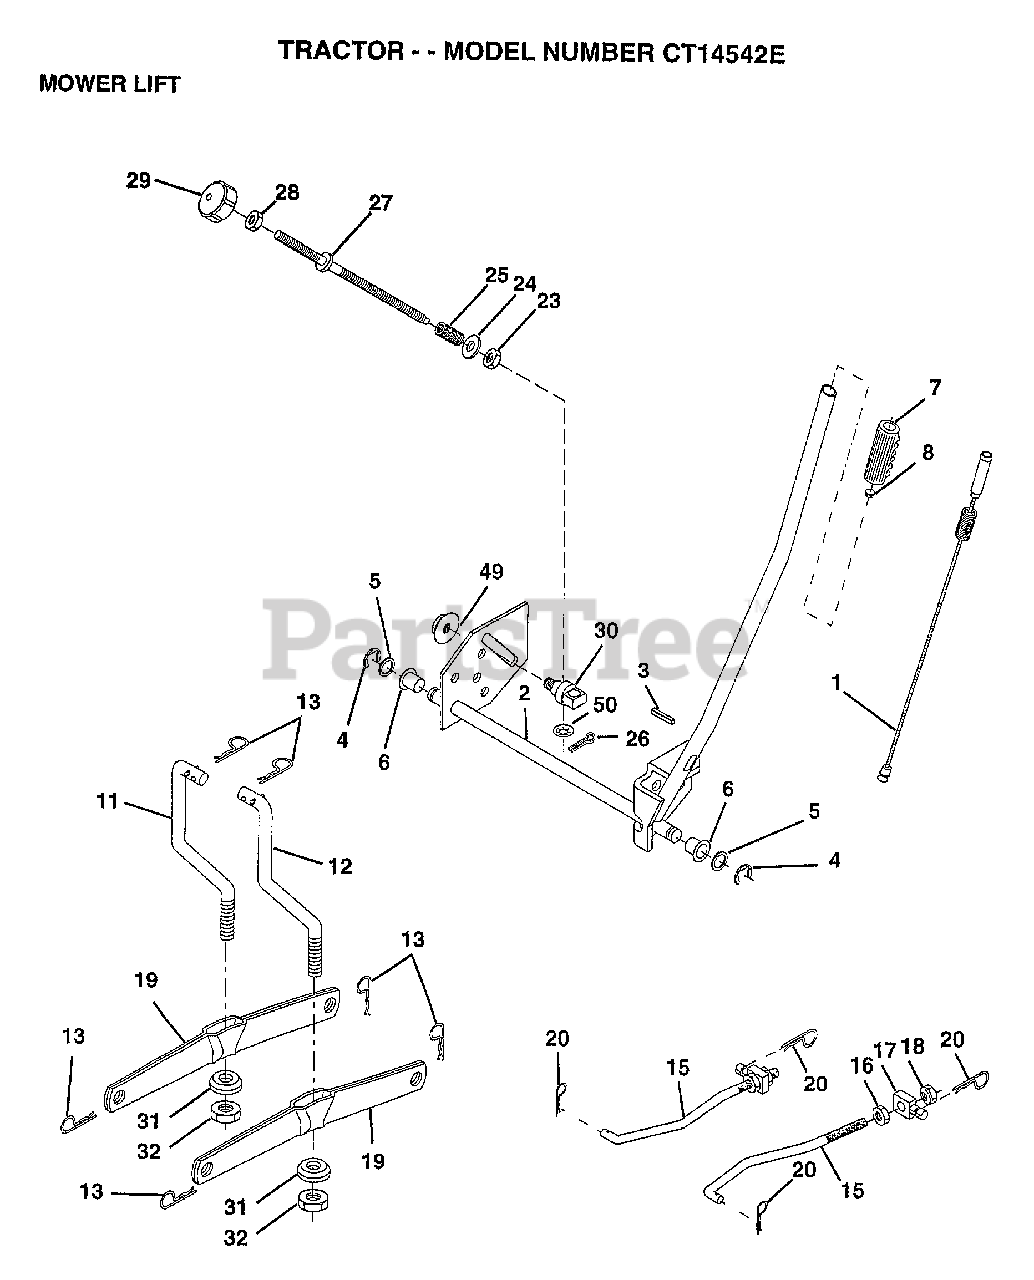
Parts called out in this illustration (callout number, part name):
1	WIRE.ASM.INNER.SP
2	"SHAFT AMS LIFT,RH"
3	PIN GROOVE
5	WASHER
6	NYLON BEARING
7	GRIP
15	LINK.FRONT
16	NUT
17	TRUNION
18	NUT.LK.W/WSH.1/2.
19	ARM SUSP REAR
20	RETAINER.SPRING
23	NUT T
24	WASHER
25	SPRING.COMP.INF.H
27	ROD.ADJ.LIFT
28	NUT
29	KNOB INF 3/8-16
30	TRUNNION
31	BEARING PVT LH
32	NUT.CROWNLOCK.3/8
49	NUT.HXFLG.LOCK.
50	NUT PUSH M
